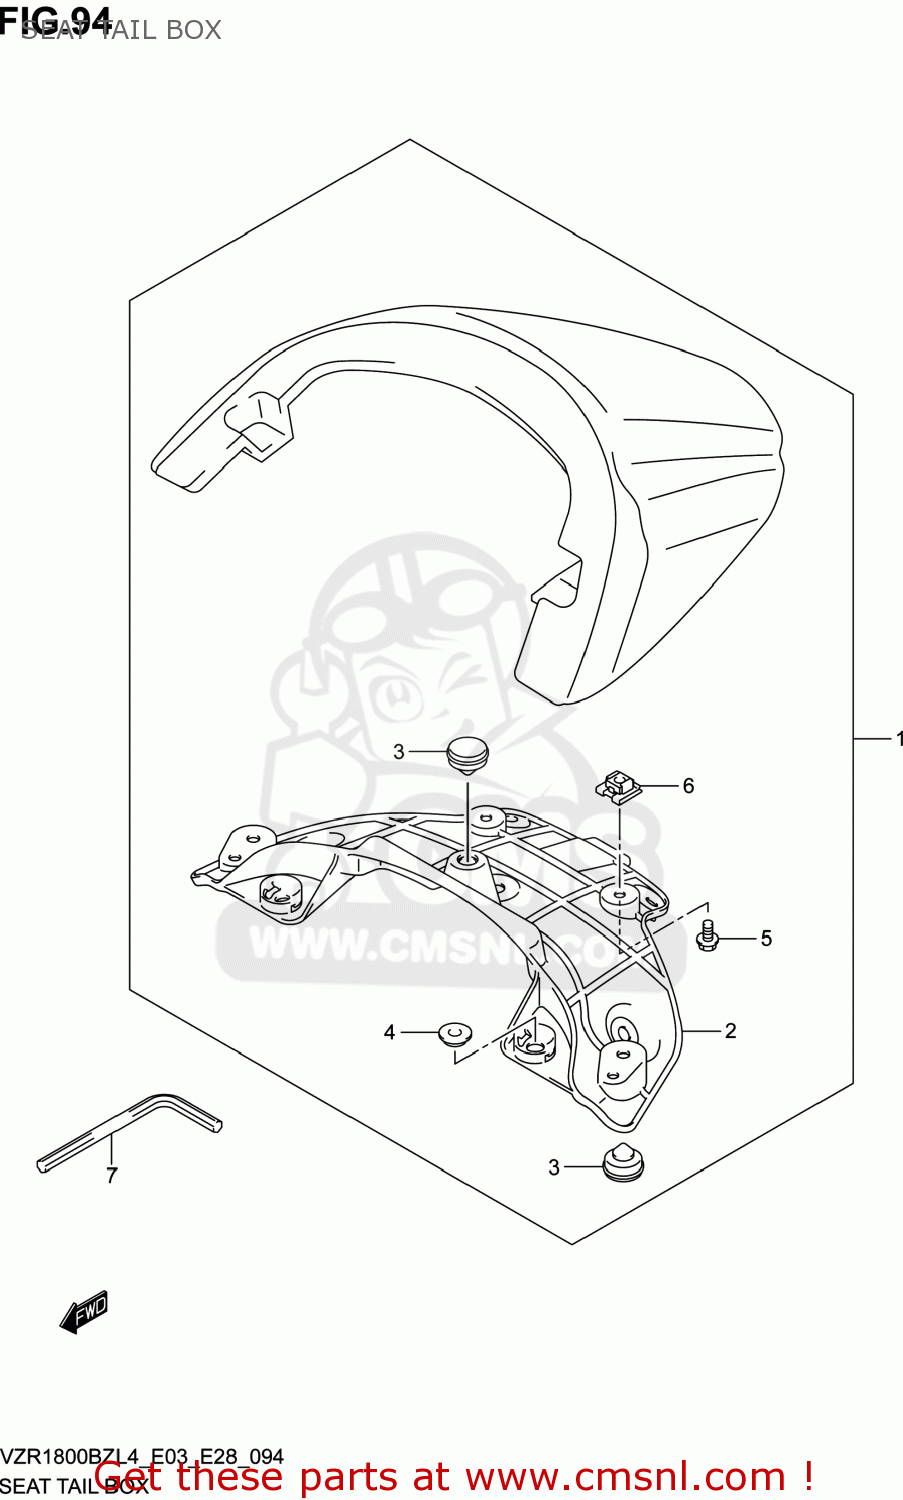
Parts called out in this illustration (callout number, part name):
1	BOX ASSY,SEAT TAIL
2	BOTTOM,SEAT TAIL BOX
3	CUSHION,FR
4	COLLAR
5	BOLT
6	NUT
7	HEXAGON SPANNER,5
